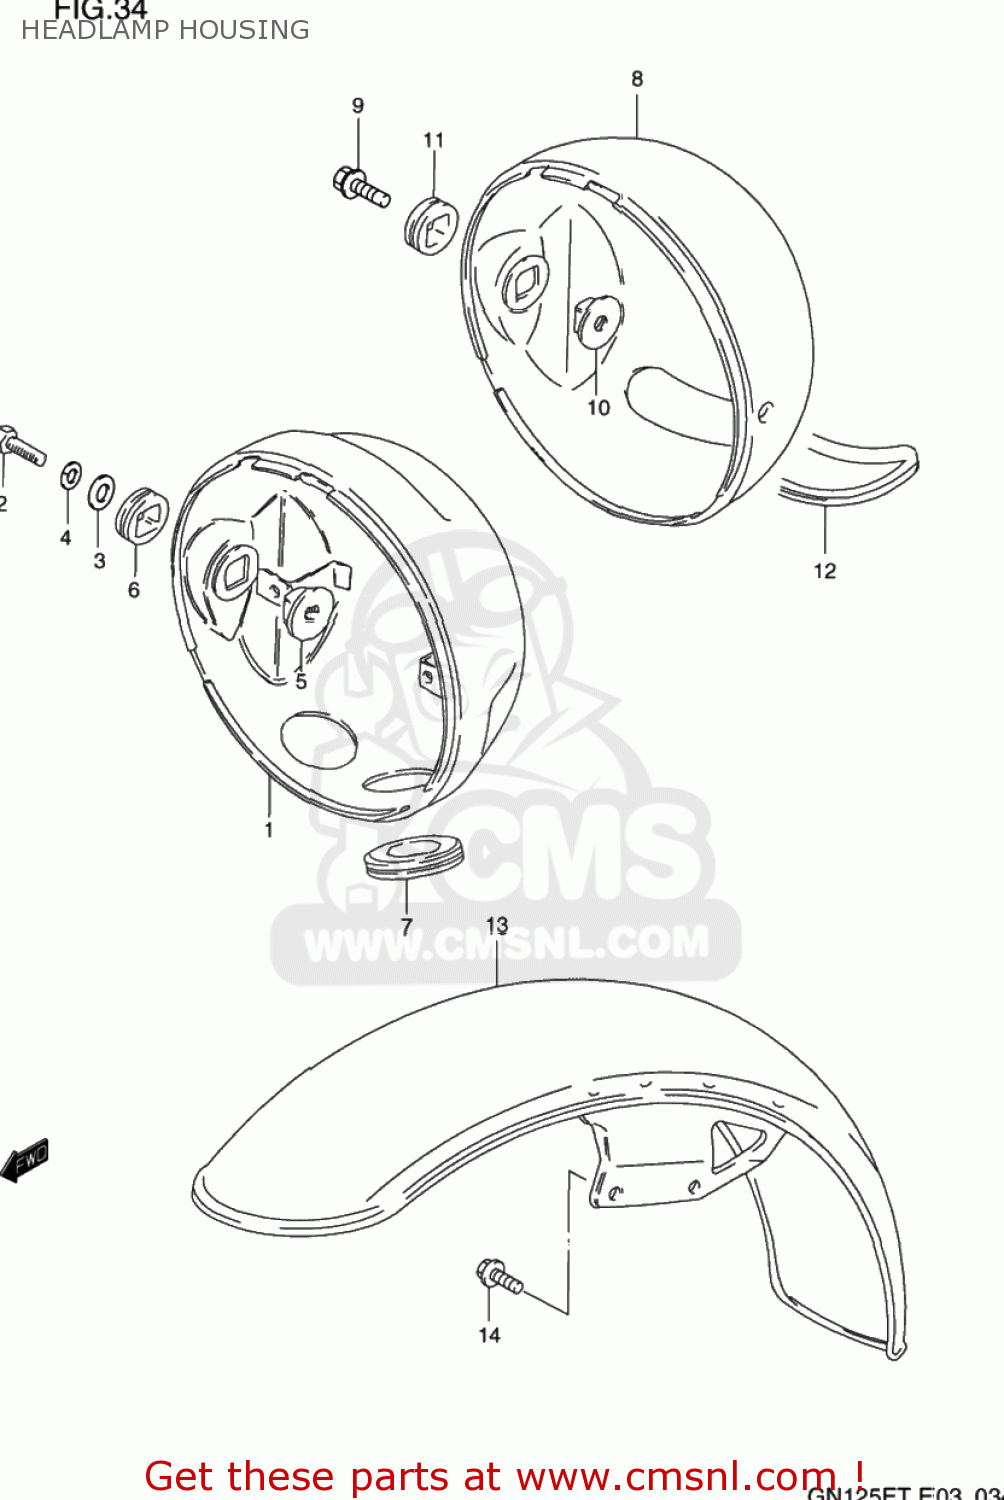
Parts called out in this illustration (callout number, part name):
1	HOUSING,HEADLAMP
2	BOLT
3	WASHER
4	WASHER,LOCK
5	SPACER,HEADLAMP HOUSING
6	CUSHION,HEADLAMP HOUSING
7	GROMMET,HEADLAMP HOUSING
8	HOUSING,HEADLAMP
9	BOLT
10	SPACER,HEADLAMP HOUSING
11	CUSHION,HEADLAMP HOUSING
12	MOLDING
13	FENDER,FR
14	BOLT
